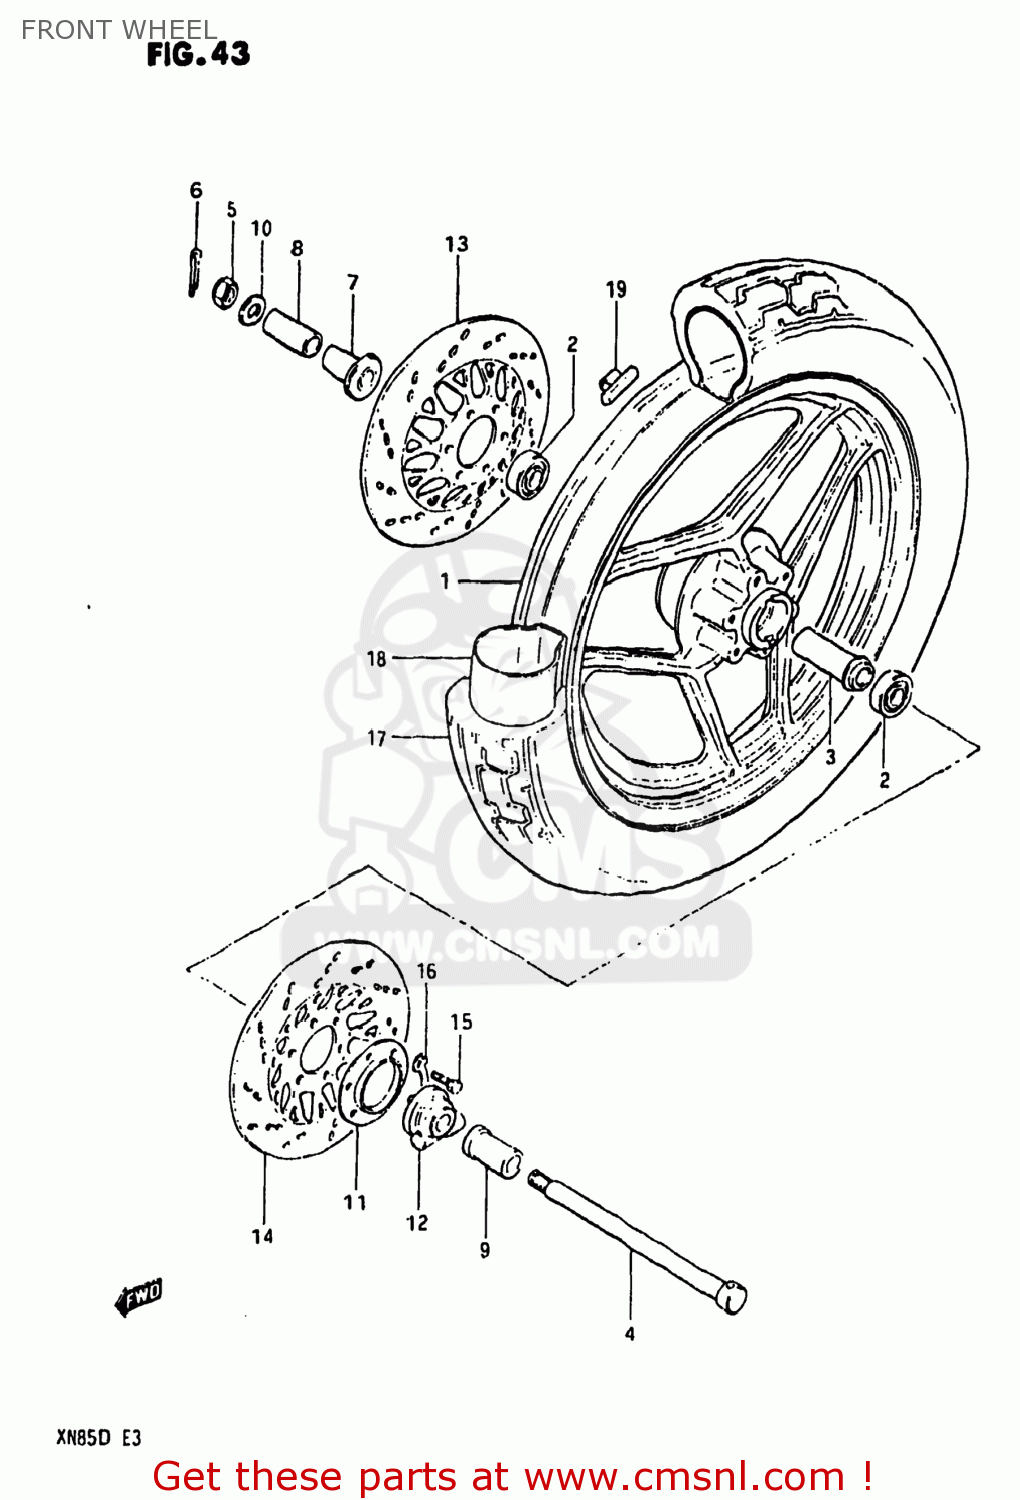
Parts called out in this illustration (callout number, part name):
1	CASTING WHEEL,FRONT 2.15
2	BEARING
3	SPACER,FRONT HUB BEARING
4	AXLE,FR
5	NUT 12MM
6	COTTER PIN
7	SPACER,FR AXLE,R
8	SPACER,FR AXLE,R
9	SPACER,FR AXLE,L
10	WASHER
11	DUST SEAL,SPEEDOMETER GEAR BOX
12	BOX ASSEMBLY,SPEEDOMETER GEAR
13	DISC,BRAKE,RIGHT
14	DISC,BRAKE,LEFT
15	BOLT(8X28)
16	WASHER
17	TIRE,FRONT
18	TUBE,INNER
19	BALANCER,WHEEL
